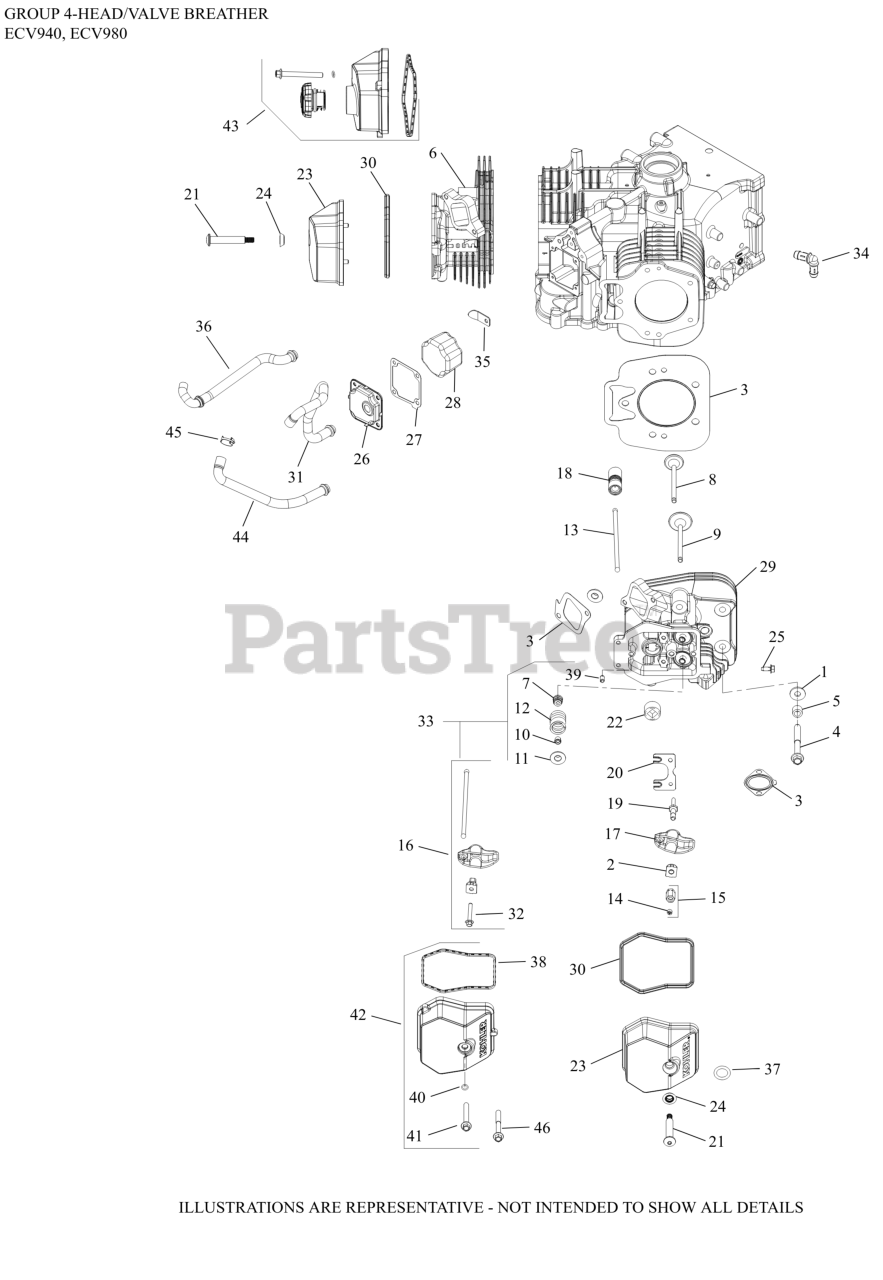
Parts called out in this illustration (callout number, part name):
1	WASHER, FLAT 13/32"
2	PIVOT, ROCKER ARM
3	KIT, CYLINDER HEAD GASKET
4	SCREW, FLG M10X1.5X90
6	HEAD CYLINDER #1-USE 62 318 42-S
7	SEAL, VALVE BAND
8	VALVE, EXHAUST
9	VALVE, INTAKE
10	KIT, RETAINER
11	CAP, VALVE SPRING
12	SPRING, VALVE
13	ROD, PUSH
17	ARM, ROCKER
18	LIFTER, VALVE HYDRAULIC-USE 25 351 11-S
21	SCREW, SHOULDER
22	PLUG, PIPE 3/4 NPTF SQUARE
23	KIT,COVER VALVE(NO OIL FILL)-(#6209650S)
24	GROMMET, VALVE COVER SCREW
25	SCREW, THREAD FORMING
26	KIT, BREATHER ASSEMBLY
27	GASKET, BREATHER
28	FILTER, BREATHER
29	HEAD CYLINDER #2-USE 62 318 43-S
30	SEAL, VALVE COVER
31	HOSE, BREATHER
32	SCREW, FLG M6X1.0X45-USE 25 086 764-S
